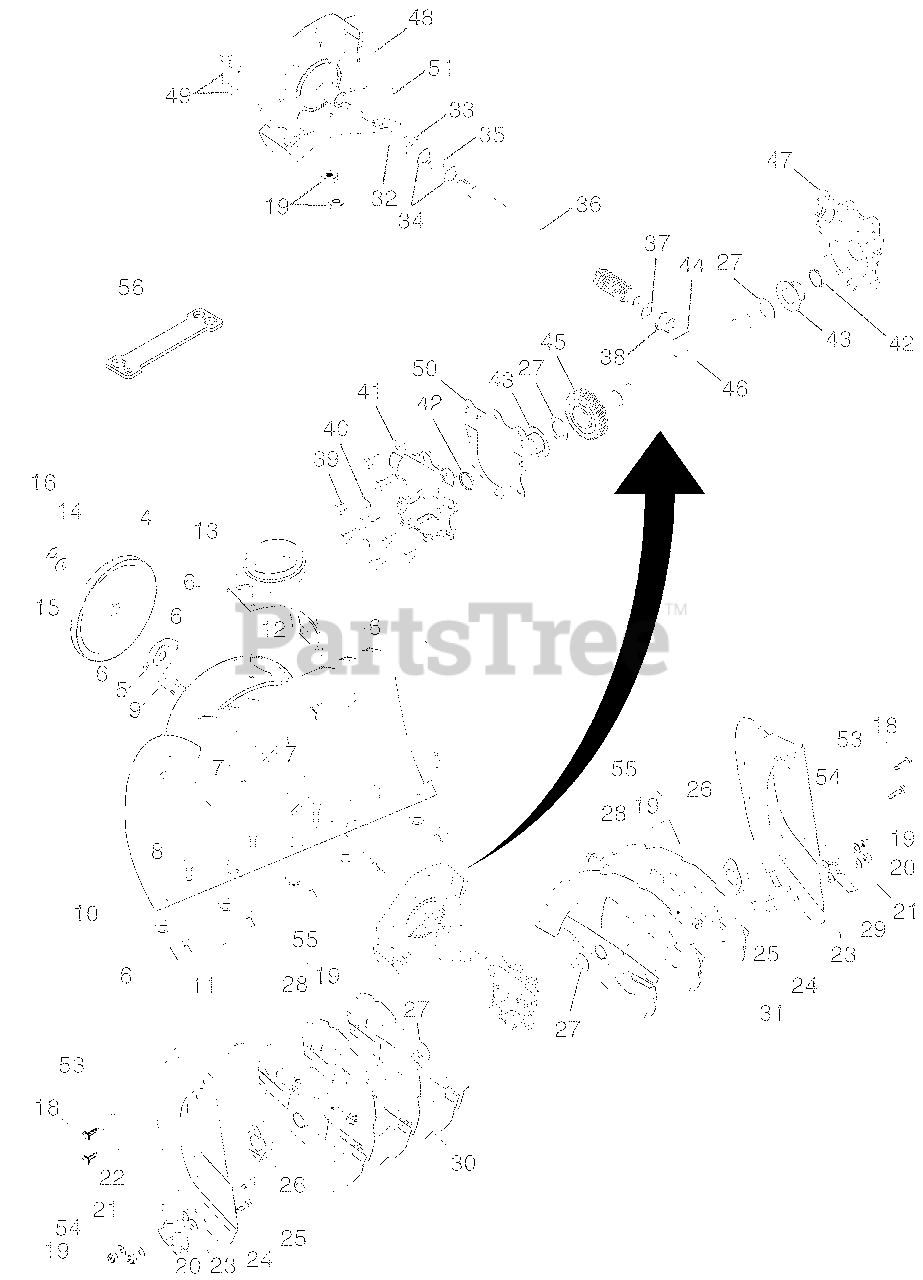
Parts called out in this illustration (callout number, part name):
4	Pulley, Impeller
5	Bearing Assembly, Flange
6	Nut, Hex Flange 5/16-18
7	Bolt, Flat Head, Carriage 5/16-18 x 5/8
8	Bolt, Carriage 5/16-1 8 x 5/8
9	Nut, Cage 3/8-16
10	Housing, Auger
11	Bar, Scraper
12	Bracket, Corner Discharge
13	Base, Discharge Chute
14	Washer, Flat
15	Washer, Lock 5/16
16	Screw, Hex Head 5/16-18 x 3/4
18	Screw, Hex Head 5/16 x 1
19	Nut, Hex Lock 1/4-20
20	Nut, Hex Lock 5/16-18
21	Washer, Flat 5/16
22	Skid Plate, RH
23	Washer, Nylon, Friction
24	Bolt, Carriage 5/16-18 x 3/4
25	Bolt, Shoulder 1/4-20
26	Bearing Retainer, Plastic
27	Washer, Thrust, 1"
28	Bolt, Shear
29	Skid Plate, LH
30	Auger Assembly, RH
31	Auger Assembly, LH
33	Bushing, Flange 3/4
34	Washer, Thrust 3/4
35	Bearing, Thrust 3/4
36	Shaft, Impeller
37	Washer, Thrust 5/8
38	Bushing, Flange 5/8
39	Screw, Hex Head 5/16-18 x 3/4
40	Plug, Case
41	Housing, Gearbox, RH
43	Bushing, Flange, 1"
44	Key, Square 1/4 x 1/4 x 7/8
45	Gear, Worm
46	Shaft, Auger
47	Housing, Gearbox, LH
48	Impeller Assembly
49	Screw, Hex Head 1/4-20 x 1-5/8
50	Gasket, Gearbox
51	Pin, Roll 3/16 x 1-1/8
53	Bearing, Auger
54	Washer, Flat 1/4
55	Kit, Shear
56	Multi-Wrench
